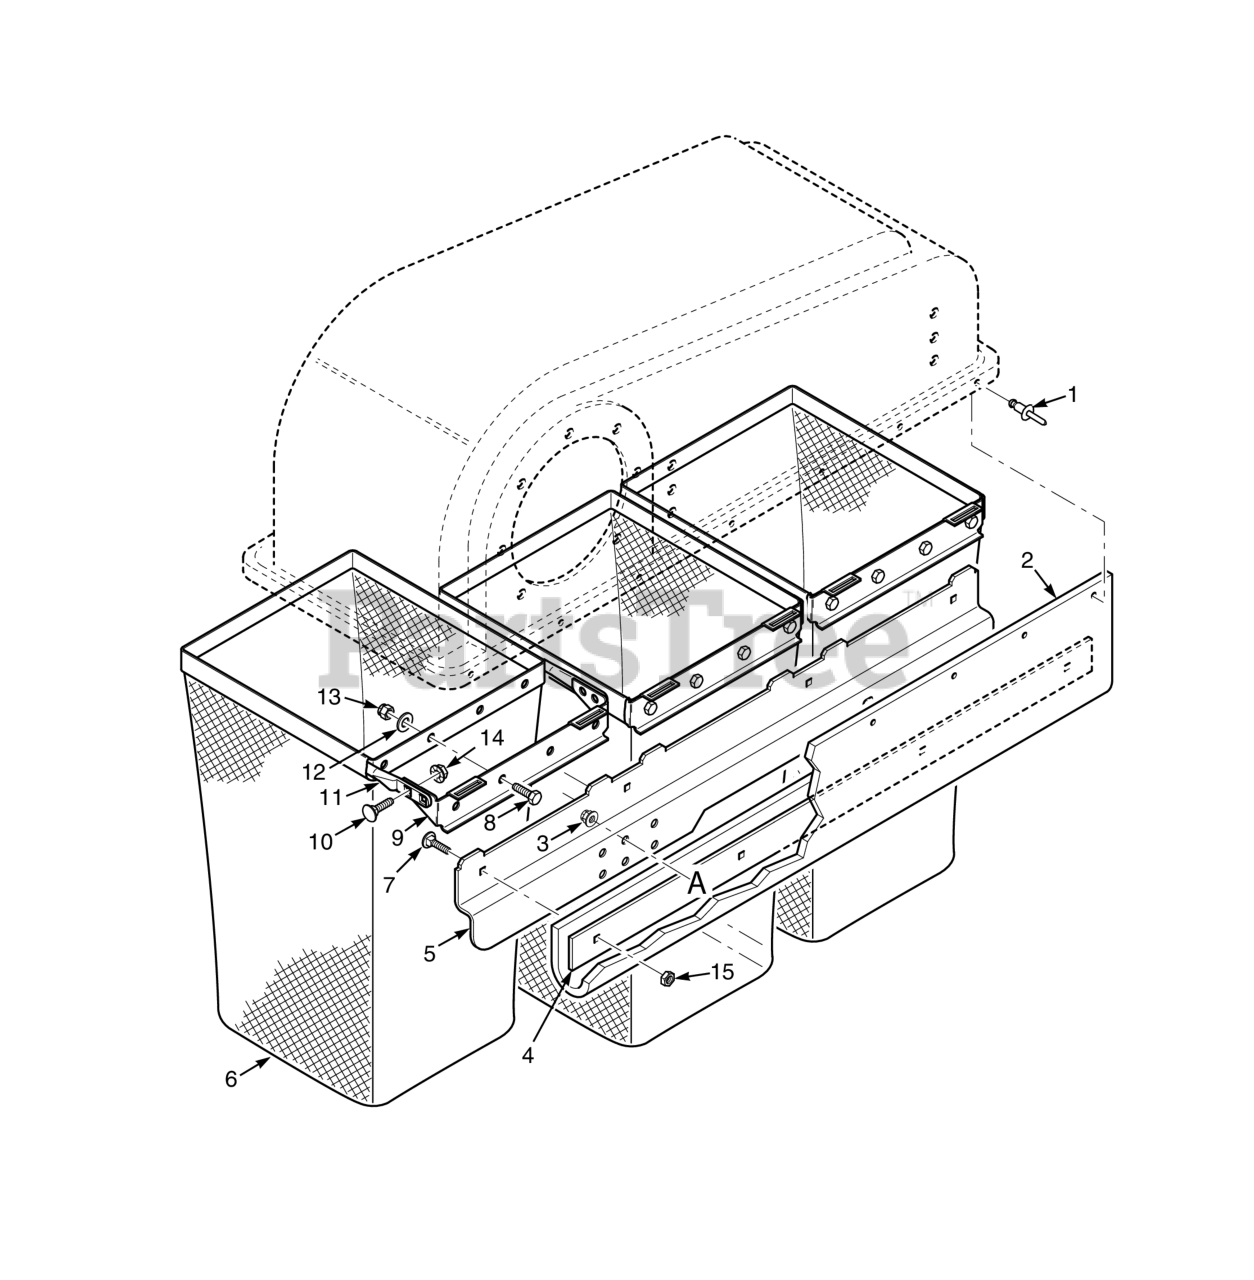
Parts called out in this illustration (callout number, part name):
1	Pop Rivet, 3/16 x .652"
2	Seal, Hood
3	Nut, Flange Elastic Stop Nut, 3/8-16
4	Retainer, Seal
5	Support Weldment, Bag Frame
6	BAG ASSY, GC
7	Serr. Fl. Hex Head CPSCR, 1/4-20 x 3/4"
8	BOLT, SERRATED FLANGE HEX HEAD 5/16-18 X 3/4"
9	Mount, Bag Frame Tube
10	Bolt, 5/16-18 x .75 RHSN Carriage
11	Tube, Bag Support
12	Flatwasher, 5/16-.375 x .875 x .083 (35BV & 37BV-EFI)
13	HEX NUT, ELASTIC STOP LOCK, 5/16-18
14	Nut, Serrated Flange 5/16-18 (Right Front Engine Mounting, Briggs and Kohler Only)
